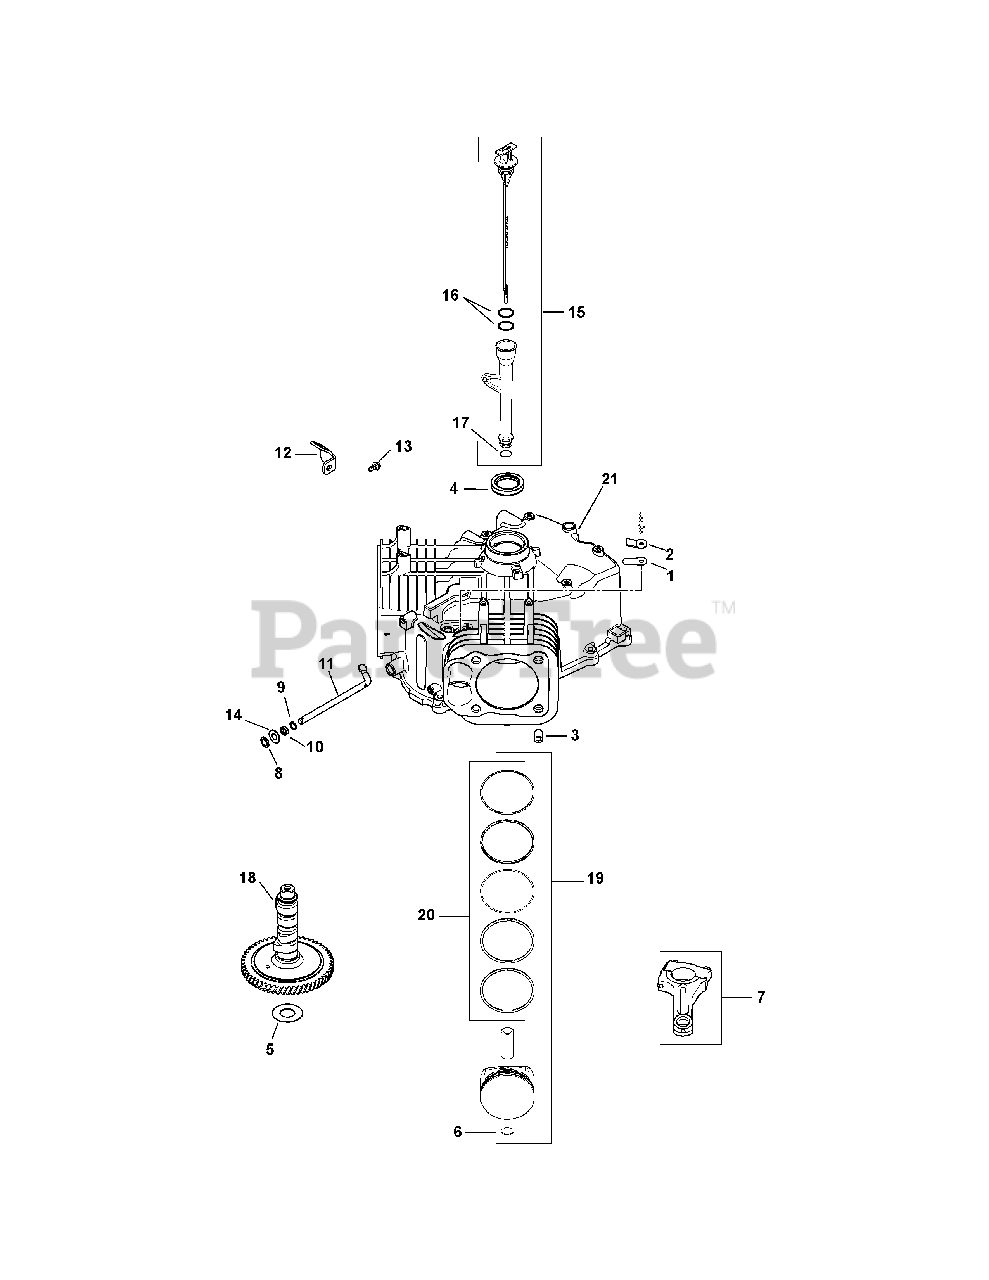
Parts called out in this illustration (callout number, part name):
1	Breather Reed
2	Breather Reed Retainer
4	Oil Seal, 1.78 x 1.26
5	Camshaft Shim (White, .028)
5	Camshaft Shim (Blue, .03)
5	Camshaft Shim (Red, .032)
5	Camshaft Shim (Yellow, .034)
5	Camshaft Shim (Green, .036)
5	Camshaft Shim (Gray, .038)
5	Camshaft Shim (Black, .04)
6	Piston Pin Retainer
7	Connecting Rod (STD)
8	Ring Retainer
9	Flat Washer, 11/32
10	Governor Cross Shaft Seal
11	Governor Cross Shaft
12	Oil Fill Tube Bracket
13	Flange Screw, M5 x .8 x 13
14	Flat Washer, 9mm
15	Dipstick & Tube Kit
17	Lower Oil Fill Tube O-Ring
18	Camshaft Assembly
19	Piston Kit w/ Ring
19	Piston Kit w/ Ring (0.25) 83mm
19	Piston Kit w/ Ring (0.08) 83mm
20	Ring Set, Piston STD
20	Ring Set, Piston (.08)
20	Ring Set, Piston (.25)
21	Crankcase (Use Short Block)
